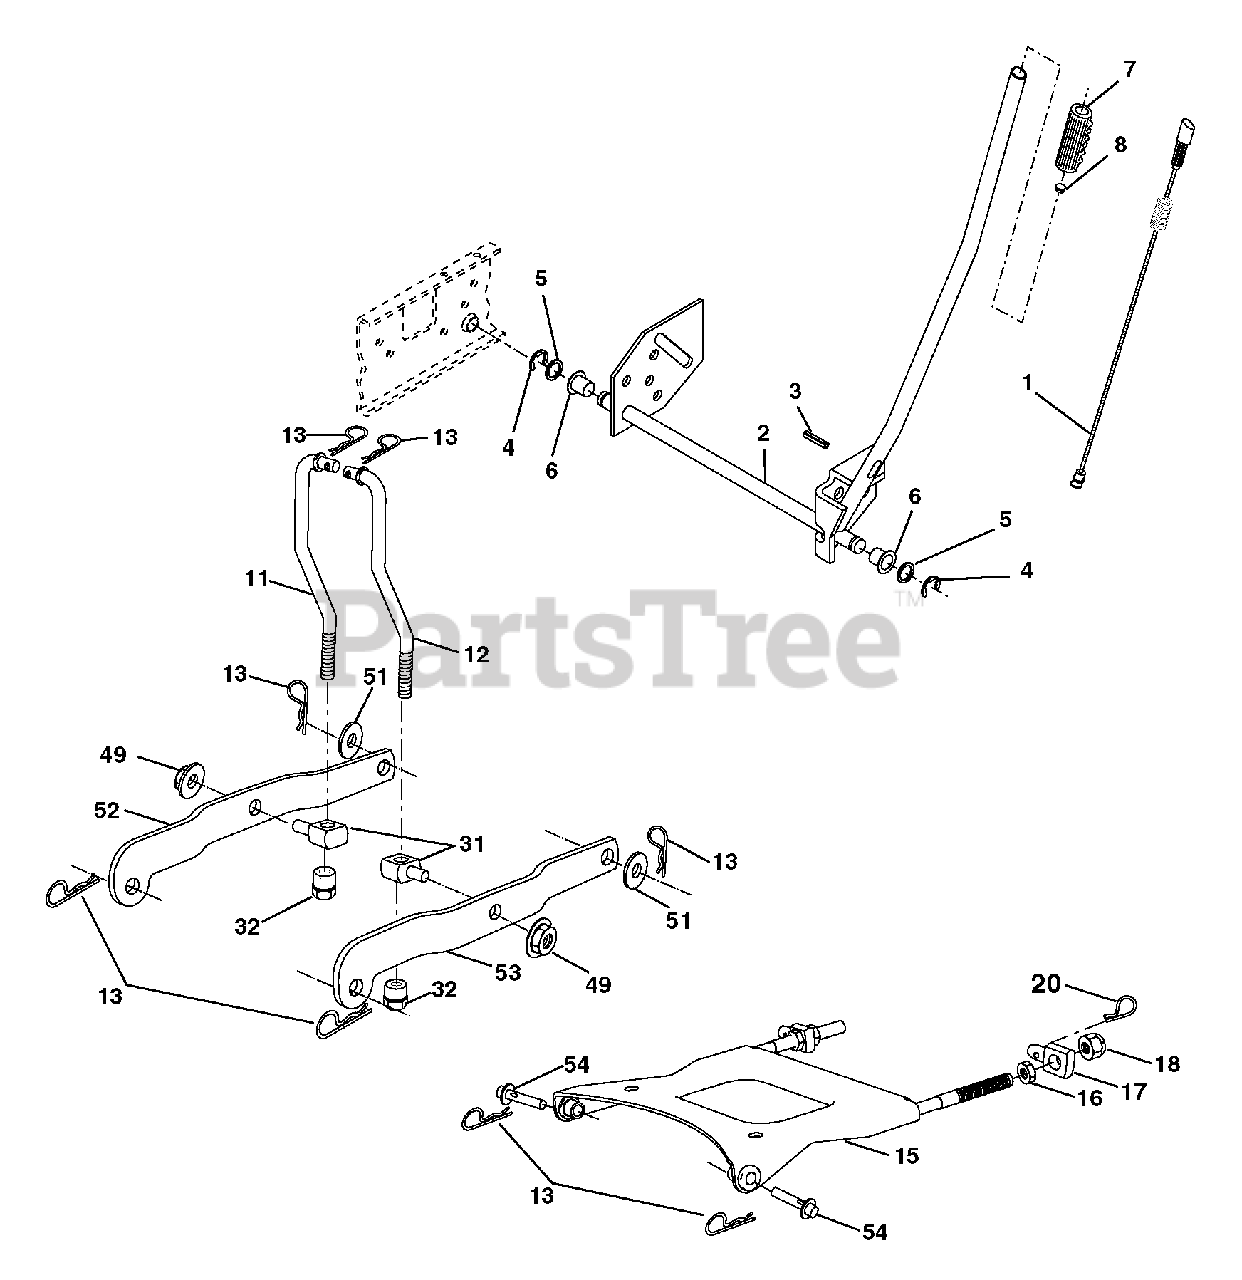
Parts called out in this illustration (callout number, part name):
1	Plunger Asm.
2	Shaft Asm Lift RH w/Inf
3	Pin Groove
4	E Ring #5133-62
5	Washer 21/32 x 1 x 21 Ga.
6	Bearing Nylon Blk 629 Id
7	Grip Handle
8	Button Plunger
11	Link Lift LH
12	Link Lift RH
13	Retainer Spring
15	Plate Asm. Suspension Front
16	Nut Jam Hex 1/2-13 unc
17	Trunnion Front Susp.
18	Nut Lock w/Wsh 1/2-13 unc
20	Retainer Spring
31	Trunnion Susp. Arm
32	Nut Lift Link 7/16-20
49	Nut Hex Flange Lock
51	Washer 17/32 x 7/8 x 16 Ga.
52	Arm Susp. Rear LH
53	Arm Susp. Rear RH
